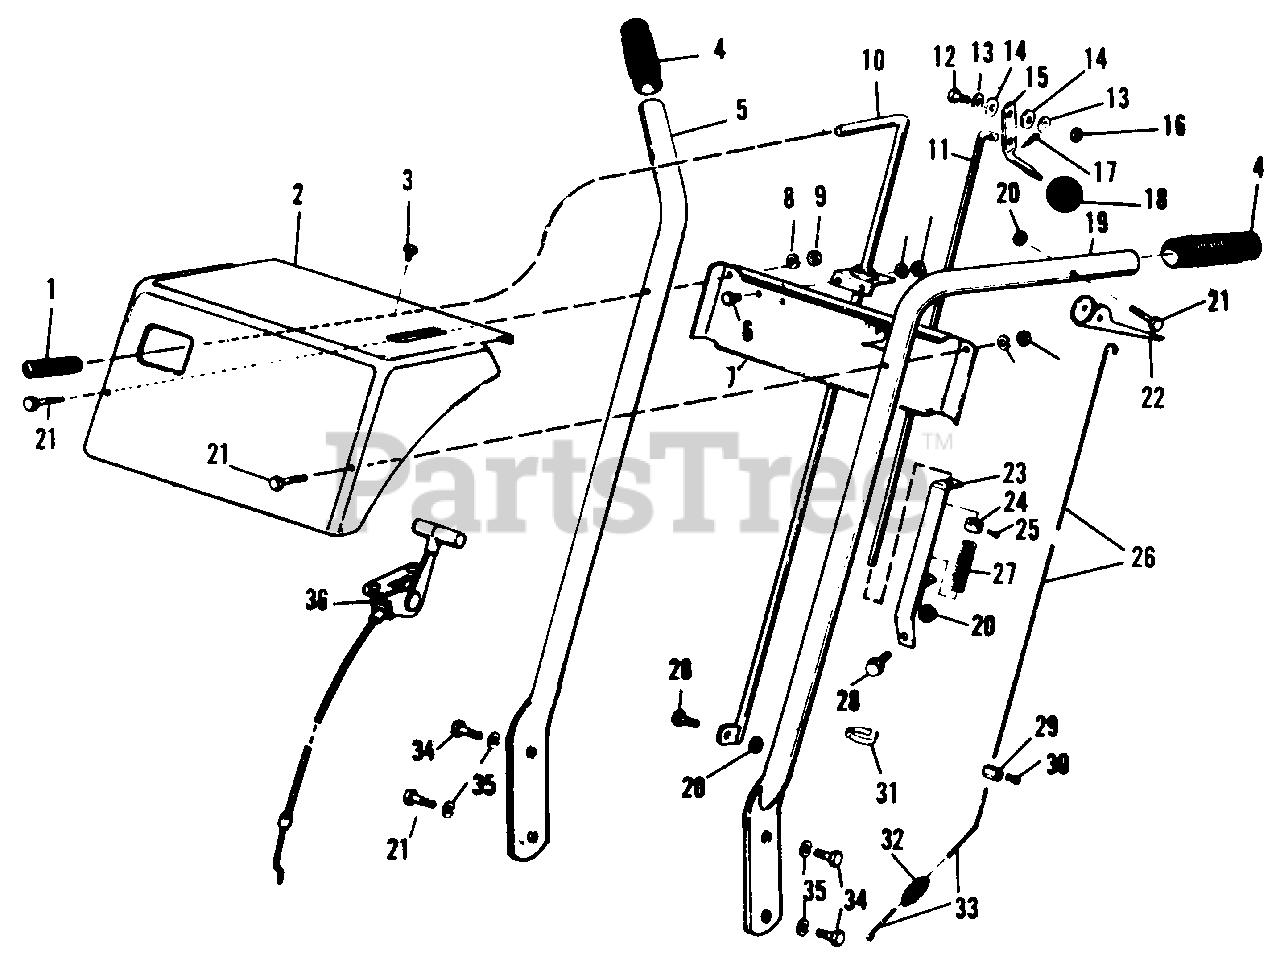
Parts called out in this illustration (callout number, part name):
1	GRIP-handle
2	HOUSING ASSY., Control (990560 Only)
3	SCREW-hex, self-tapping, 1/4-20 x 1/2
4	GRIP, Handle Bar
5	HANDLE-rear, R.H.
6	Hex. Cap Screw, 1/4"-20 x 1/2" (Not used on 308 & 314)
7	COVER-handle
8	Lock Washer, 1/4" (Not used on 308 & 314)
9	Hex Nut, 1/4"-20 (Mfg. Nos. 953 & 954)
10	SHIFT ROD ASSEMBLY
11	ROD, Clutch
12	Screw, Cap, Hex., 5/16"-18 N.C. x 7/8" lg.
13	Flat Washer, 1/4" (for service only)
14	WASHER-special
15	HANDLE-auger clutch
16	Elastic Stop Nut, 5/16"-18 N.C.
17	Pin, Cotter, 3/32" dia. x 3/4" lg., w/Ext. Prong
18	Knob
19	HANDLE-rear, L.H.
20	Nut, Lock, Full, Hex., 1/4"-20 N.C.
21	CAPSCREW, Hex, Head, 1/4"-20 NC x 1-1/2" Lg.
22	GRIP, Clutch
23	GUIDE ASSY., Rod
24	COLLAR, Set (Stand Rod)
25	Screw, Set, Square Head, Cup Point, 1/4"-20 NC x 3/8" lg.
26	EXTENSION, Spring
27	SPRING, Compression
28	Hex Capscrew, 1/4"-20 x 1 " lg.
29	CLAMP, Wire
30	SCREW-rd. hd., 10-24 x 3/8
31	CLIP, Throttle
33	EXTENSION, Wire
34	Capscrew, Hex, 5/16"-18 NC x 3/4" lg.
35	Lockwasher, External 1/4" (Mfg. Nos. 953 & 954)
36	THROTTLE CONTROL ASSEMBLY
